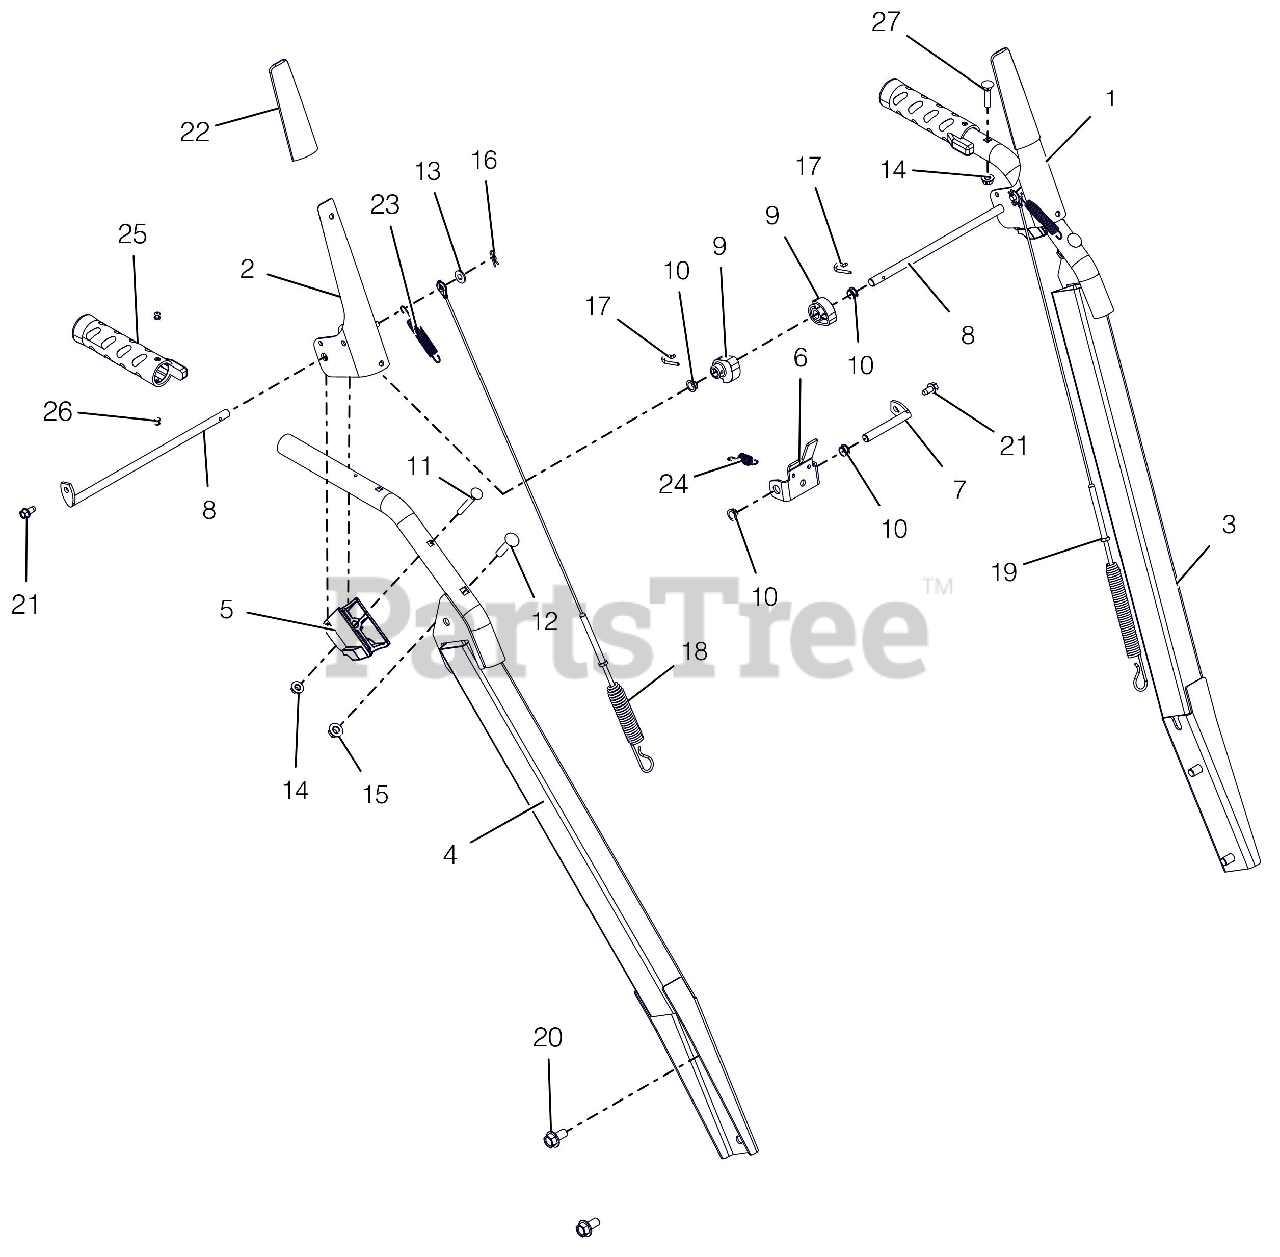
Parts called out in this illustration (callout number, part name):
1	LEVER, CLUTCH-LH
2	LEVER, CLUTCH-RH
3	HANDLEBAR, HEAVYDUTY-PRO LH
4	HANDLEBAR, HEAVYDUTY-PRO-RH
5	BLOCK, CLUTCH PADDLE
6	BRACKET, INTERLOCK ARM
7	ROD, PIVOT - INTERLOCK
8	ROD, PADDLE MOUNT - PRO
9	CAM, INTERLOCK
10	BUSHING, POLYLINER-.38 SNAPIN
11	BLT-RDHDXLSQNK .25-20X2.0 G5YZ
12	@BLT-RDHDSQNK .31-18X1.50 G5YZ
13	@WSHR-FL-STL.281X.62X.065 YWZC
14	@NUT-LK-CTR-FLG .25-20 YWZC
15	@NUT-LK-TOP-FLG .31-18 YWZC
16	PIN-HAIR INT .06X.18X.77
17	PIN, SPRING CLIP
18	CABLE, AUGER (DELUXE & PRO)
19	CABLE, UPPER TRACTION
20	BLT-SERHFWH .38-16X.75 YWZC
21	SCR-TAP .25-20X.50 HWH TR YWZ
22	SLEEVE, CLUTCH PADDLE-GRAY
23	SPRING, EXTENSION
24	SPRING-EXT .047X.438X1.45
25	GRIP,HEATED HANDLE-GRAY
26	RVT-POP #43 .125X.313 STL ZINC
27	BLT-RDHDXLSQNK.25-20X1.25 G5ZC
